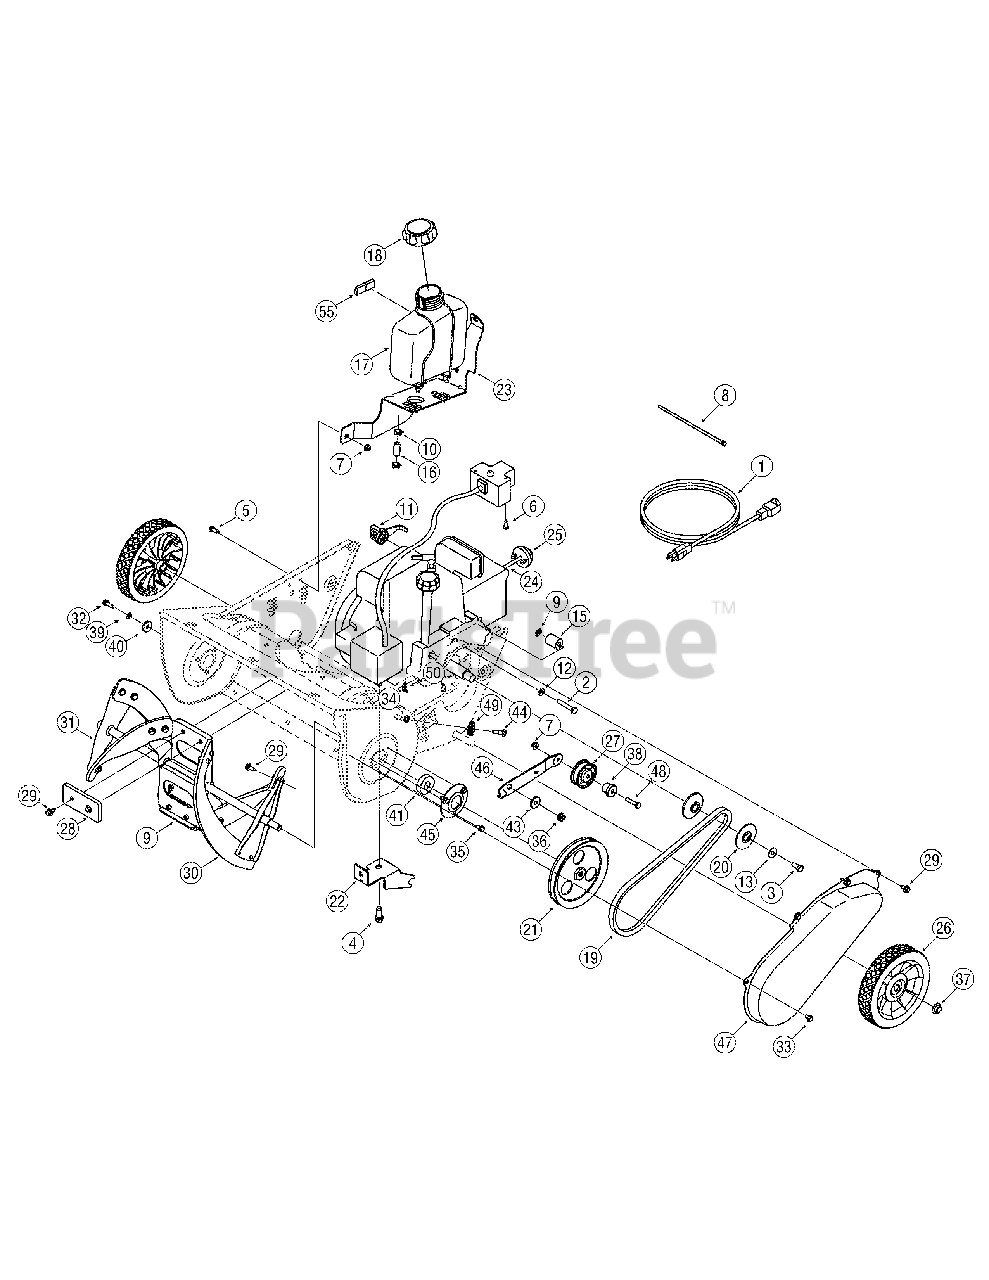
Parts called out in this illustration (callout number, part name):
1	Extension Cord
2	Hex Screw, 5/16-24 x 1.75
3	Hex Screw, 5/16-24 x .75
4	Self Tapping Screw, 3/8-16 x 1
5	Hex Screw, 1/4-20 x .62
6	Screw, #10-16 x .625
7	Hex Flange Lock Nut, 1/4-20
8	Push Mount Cable Tie
9	Auger Assembly
12	Washer, Lock 5/16
13	Flat Washer .340 x .872 x .060
14	Gas Tank Support Wire
15	Spacer, Engine
16	Hose, Fuel Line
17	Tank, Fuel
18	Cap, Fuel
19	V-Belt, 1/2
20	Pulley Half, .625 ID x 2.25 OD
21	Pulley, 1/2 x 6.0 OD
25	Primer
26	Wheel 5 Lug Diamond Design
27	Idler Pulley (1/4" hole)
28	Rubber Paddle
29	Hex Screw, 1/4-20 x .62
30	Cresent Spiral
31	Auger Axle Assembly
32	Hex Screw 1/4-20 x .75 Gr. 5
33	Self-tapping Screw 1/4-20 x .375
34	Hex Lock Nut 1/4-28
35	Self-tapping Screw, 1/4-14 x .375"
36	Hex Flange Lock Nut, 5/16-18
37	Push Cap, 1/2"
38	Shoulder Spacer .260 x .785 x .538
39	Lock Washer, 1/4
40	Flat Washer .265 x .938 x .120
41	Ball Bearing .625 x 37 x 12
43	Shoulder Spacer .25
44	Carriage Screw 1/4-28
46	Idler Brkt. w/ brake (Pulley hole 1/4")
48	Hex Screw, 1/4-20 x 1.00 Gr. 5
49	Cable Roller
50	Extension Spring
